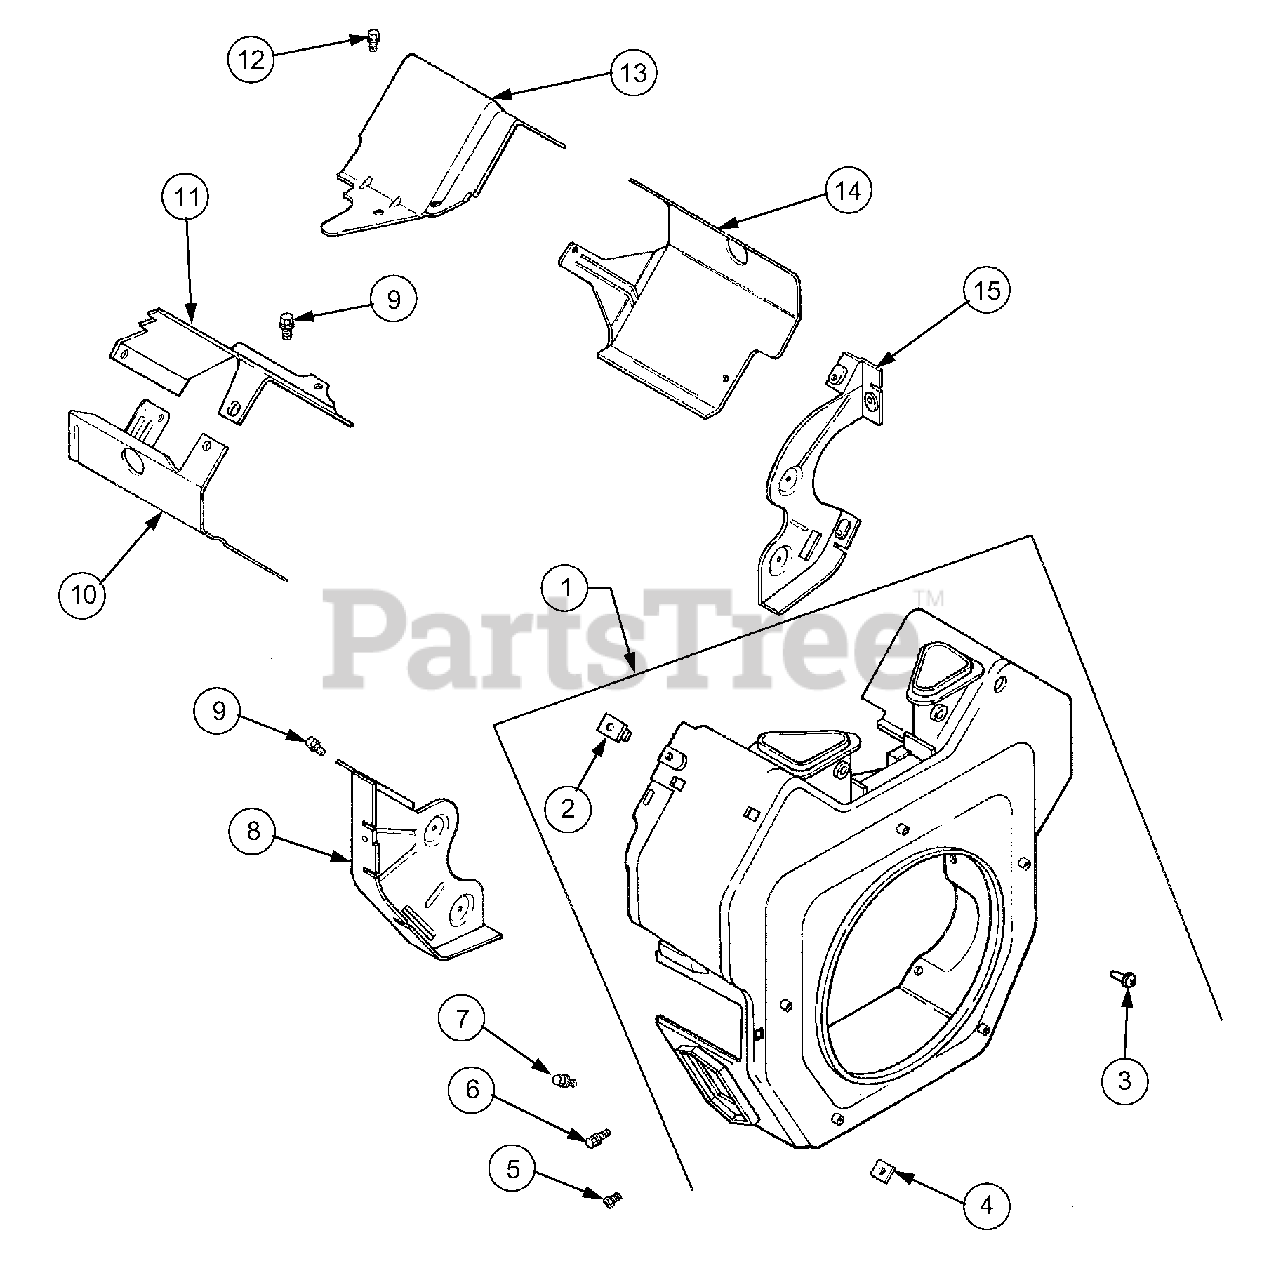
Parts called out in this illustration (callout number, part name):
1	Housing, Blower
2	Nut, Plastic
3	Screw, Tapping
4	Nut, Plastic
5	Screw, Hex Flange, M5 x 0.8 x 16
6	Screw, Hex Flange, M5 x 0.8 x 16
7	Screw, Hex Flange, M5 x 0.8 x 20
8	Plate, Backing - #2 Side
9	Screw, Hex Flange, M6 x 1.0 x 16
10	Baffle, Cylinder Barrel - #2 Side
11	Baffle, Valley - #2 Side
12	Screw, Hex Flange, M5 x 0.8 x 10
13	Baffle, Valley - #1 Side
14	Baffle, Cylinder Barrel - #1 Side
15	Plate, Backing - #1 Side
